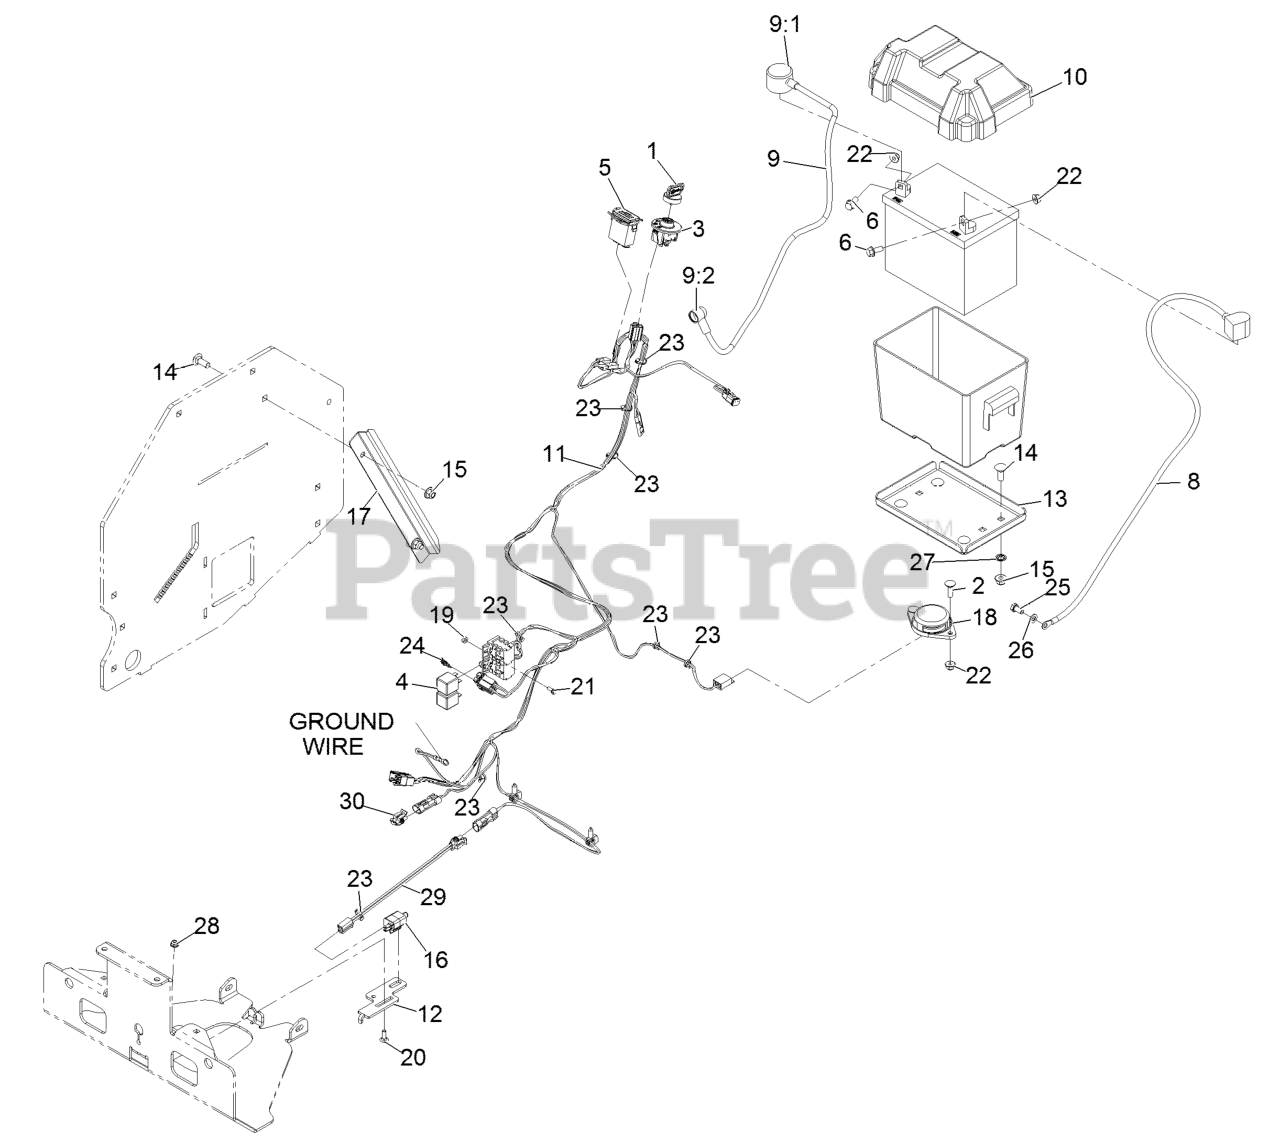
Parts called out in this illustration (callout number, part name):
1	KEYS-IGNITION (SPARE PAIR
1	KEY-IGNITION
2	BOLT-CARR
5	METER-HOUR
6	SCREW-HHF
8	CABLE-BATTERY, BLACK
9	POSITIVE BATTERY CABLE AS
9:1	INSULATOR-BATTERY
9:2	INSULATOR-SOLENOID
10	BATTERY BOX ASM
11	HARNESS ASM
12	MOUNT-SWITCH
13	TRAY-BATTERY
14	BOLT-CARR
15	NUT-HF, NI
17	GUARD-HARNESS
18	SWITCH-SEAT
19	NUT-LOCK, NI
20	BOLT-CARR
21	SCREW-HWH
22	NUT-HF, NI
23	TIE-CABLE
24	FUSE-BLADE TYPE, 20 AMP
25	SCREW-HH
26	WASHER-PLAIN
27	NUT-PUSH
29	JUMPER-SWITCH
30	PLUG-SWITCH, NEUTRAL
